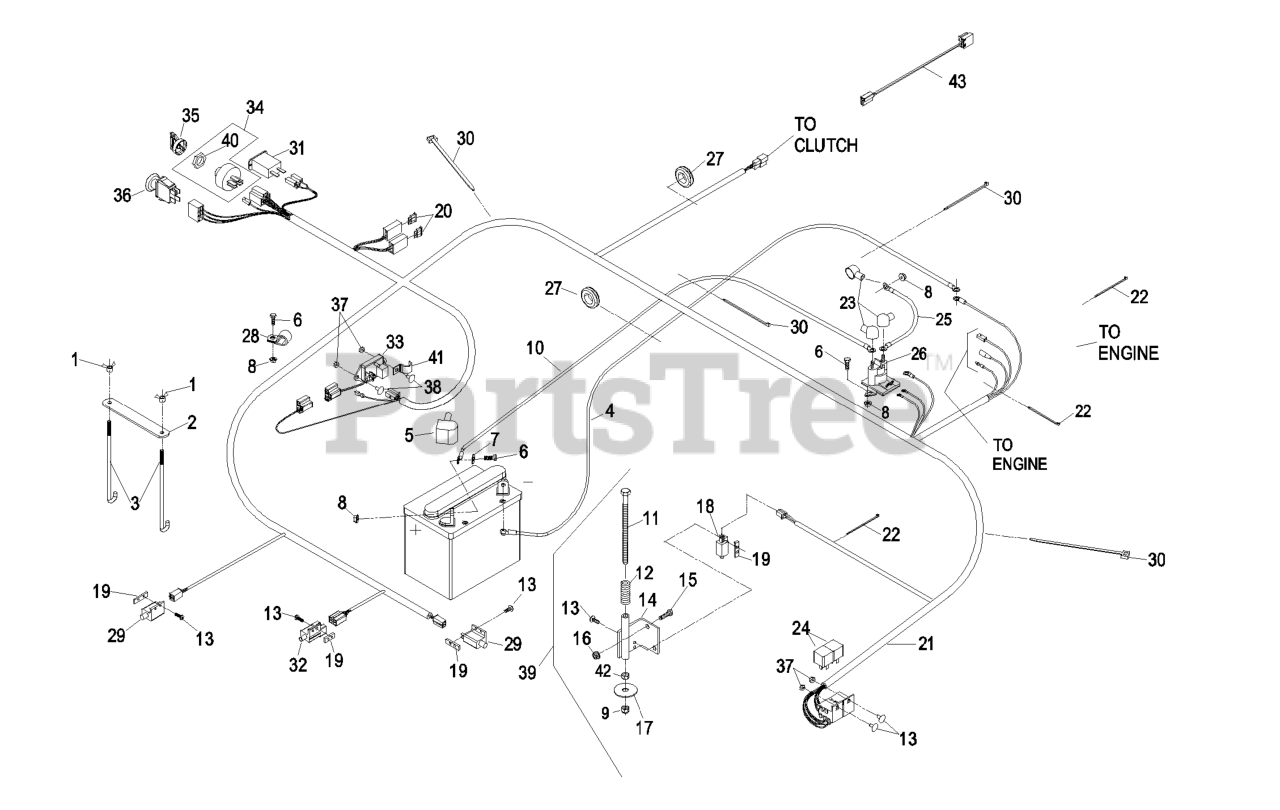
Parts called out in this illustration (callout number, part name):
1	WINGNUT
2	STRAP-HOLDDOWN, BATTERY
3	BOLT-HOLDDOWN
4	CABLE-GROUND, NEGATIVE
5	INSULATOR-BATTERY
6	SCREW-HH
7	WASHER-FLAT
9	NUT-LOCK, NI
10	POSITIVE BATTERY CABLE AS
11	SCREW-HH
12	SPRING-SWITCH, SEAT
13	SCREW-PPH
14	BRACKET-SWITCH, SEAT
15	SCREW-HH
18	SWITCH-CLOSED, NORMALLY
19	PLATE-TAPPED
20	FUSE-BLADE TYPE, 20 AMP
21	HARNESS,WIRE LHP KA
22	TIE-CABLE
23	INSULATOR-SOLENOID
25	POSITIVE STARTER CABLE AS
27	GROMMET
28	CLIP-LOOM
29	SWITCH-OPEN, NORMALLY
30	TIE-PLASTIC
31	METER-HOUR
33	MODULE-DELAY, SEAT
34	ASM,SWITCH W/NUT
35	KEY-IGNITION
36	SWITCH-PTO
37	NUT-LOCK, NI
38	SCREW-HEAD, TRUSS
39	ASM,SEAT SWITCH ACTUATOR
40	NUT-SWITCH, IGNITION
41	CLIP-HALF, LOOM
42	NUT-HEX
43	HARNESS-CLUTCH
